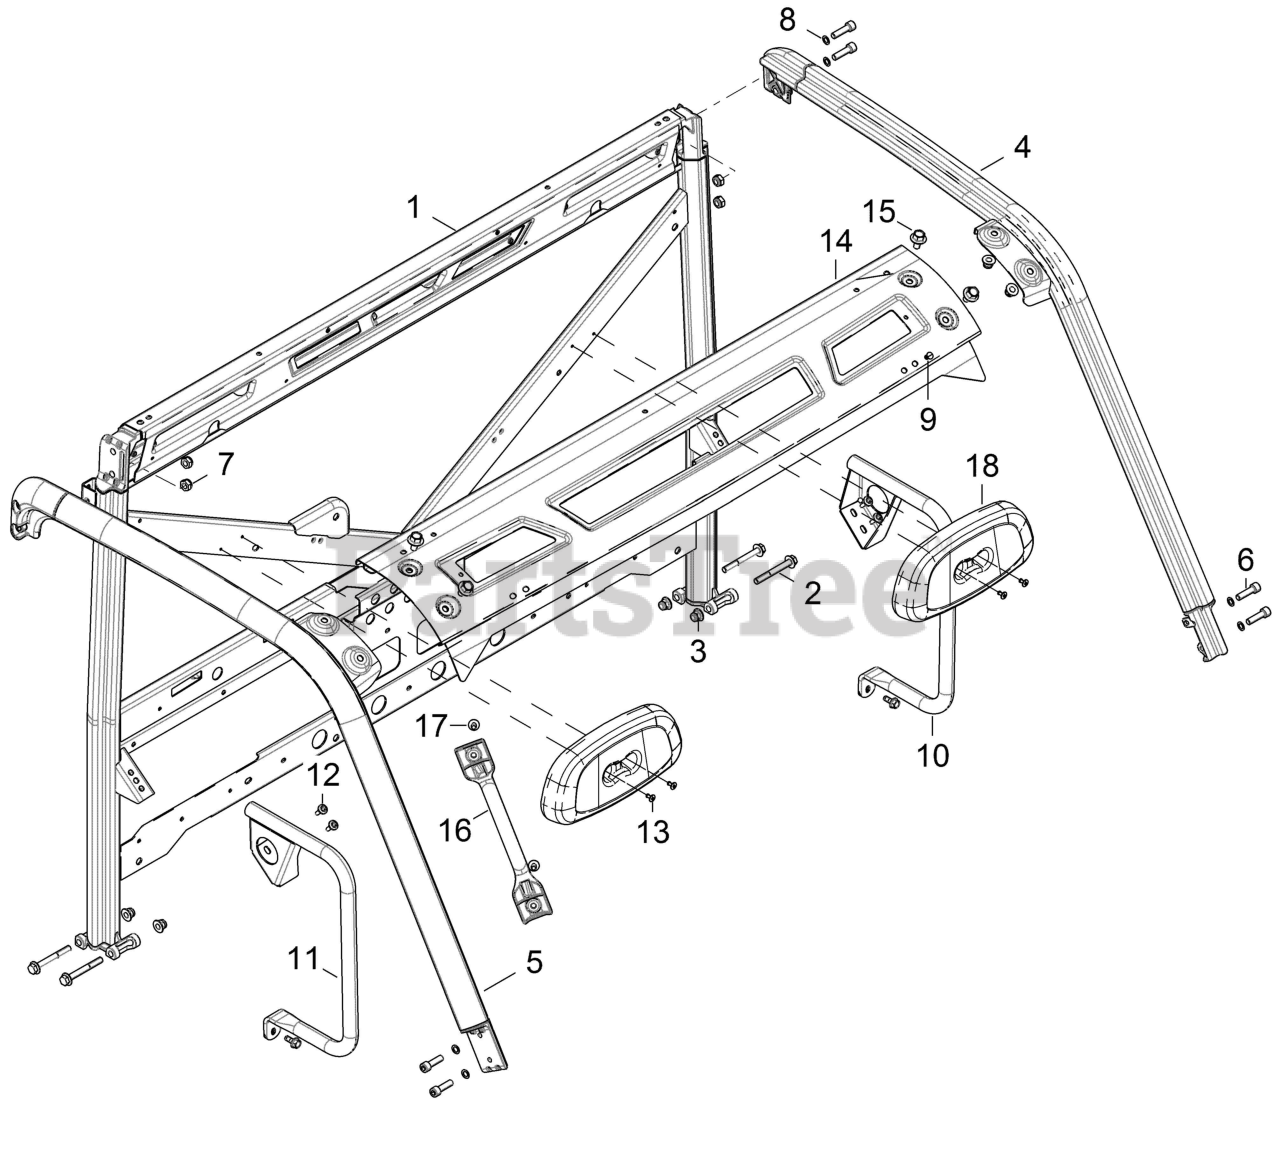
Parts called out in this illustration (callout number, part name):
1	WELD-CAB FRAME,REAR,BLK
2	SCR-HXFL-M10X1.25X80 8.8 ZOD
3	NUT-M10X1.25,FLG,NYLOC-OLIVE D
4	FRONT CAB FRAME, LH
5	FRONT CAB FRAME, RH
6	SCR-SH-M10X1.5X35 8.8 ZPB
7	NUT-NYLOC M10X1.5,REF
9	CLIP-PLASTIC,DART
10	HIP BOLSTER, LH
10	HIP BOLSTER, RH
11	SCR-HXFL-M8X1.25X20 8.8 ZOD P3
11	NUT-M10X1.25,FLG,NYLOC-OLIVE D
12	SCR-TXTH-M6X1.0X25 RIE
13	RIVET(50)
14	WELD-PLATE-WNDSHLD,UPR,CAB,BLK
15	BOLT-M10X1.5X20,HXFLG,W/PATCH
16	HANDLE-GRAB,ROPS,BLK
17	BOLT-M8X1.25X20,HXFLG,TAP/R-OD
18	HEADREST-GRAVELY,GRAY
